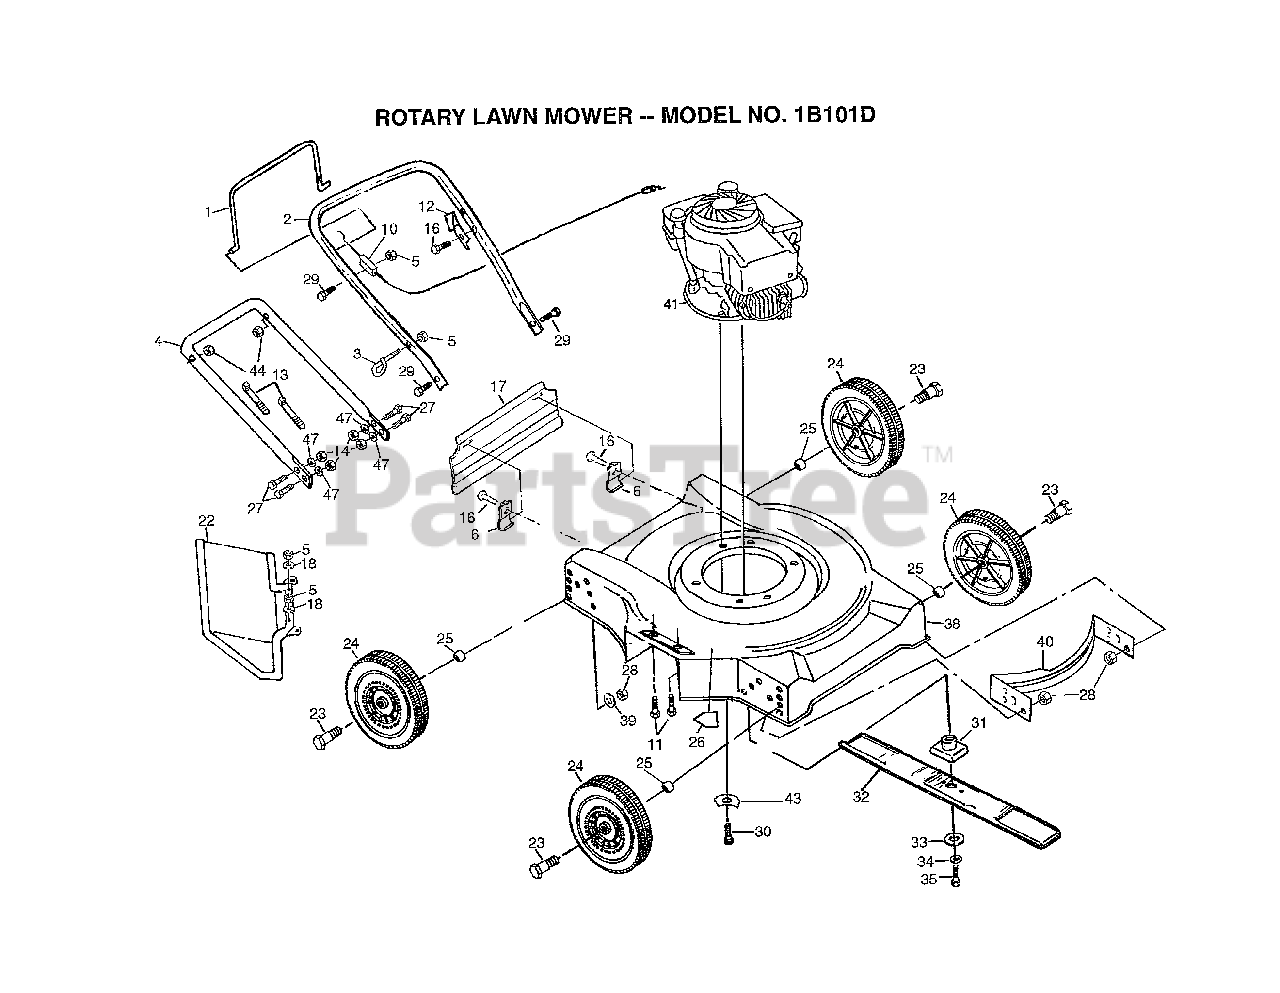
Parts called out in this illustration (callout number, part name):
1	CONTROL BAR PM
2	UPPER HANDLE
3	ROPE GUIDE
4	HANDLE LWR PM
6	"BRKT,DEFL PM"
10	CABLE.ZONE.CONTRO
11	BOLT LT
12	"BRKT,UPSTOP"
14	LOCKNUT
16	TAPPING SCREW
17	SKIRT.REAR.20RD.
22	"GRD,DISCHARGE"
23	AXLE BOLT
24	WHEEL ASSY
26	DECAL HYT
28	LOCKNUT PM
29	BOLT 1/4-20-1 1/2
30	SCREW
31	BLADE ADAPTOR
32	BLADE.20.MULCH.AY
33	"WASHER,HARDEN"
34	LOCKWASHER
35	SCREW
47	STEEL WASHER
